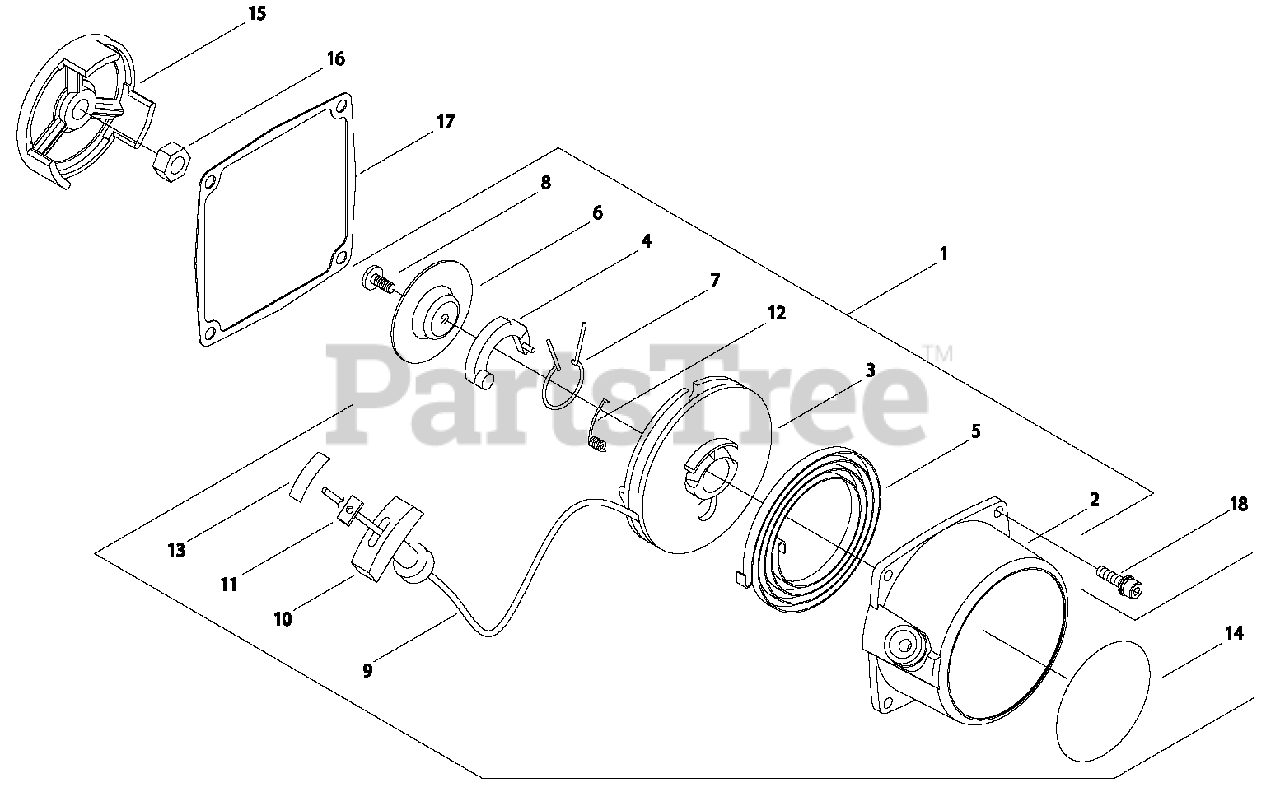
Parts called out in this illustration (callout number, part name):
1	STARTER ASSY, RECOIL
2	CASE, RECOIL STARTER
3	REEL, ROPE
4	RATCHET
5	SPRING, RECOIL
6	PLATE, FRICTION
7	SPRING, FRICTION
8	SCREW
9	ROPE, STARTER
10	GRIP, STARTER
11	RETAINER, ROPE
12	SPRING, RETURN
13	TAPE
14	LABEL, TRADE
15	PULLEY, STARTER
16	NUT M8×H5
17	GASKET, RECOIL STARTER
18	BOLT M4×16
